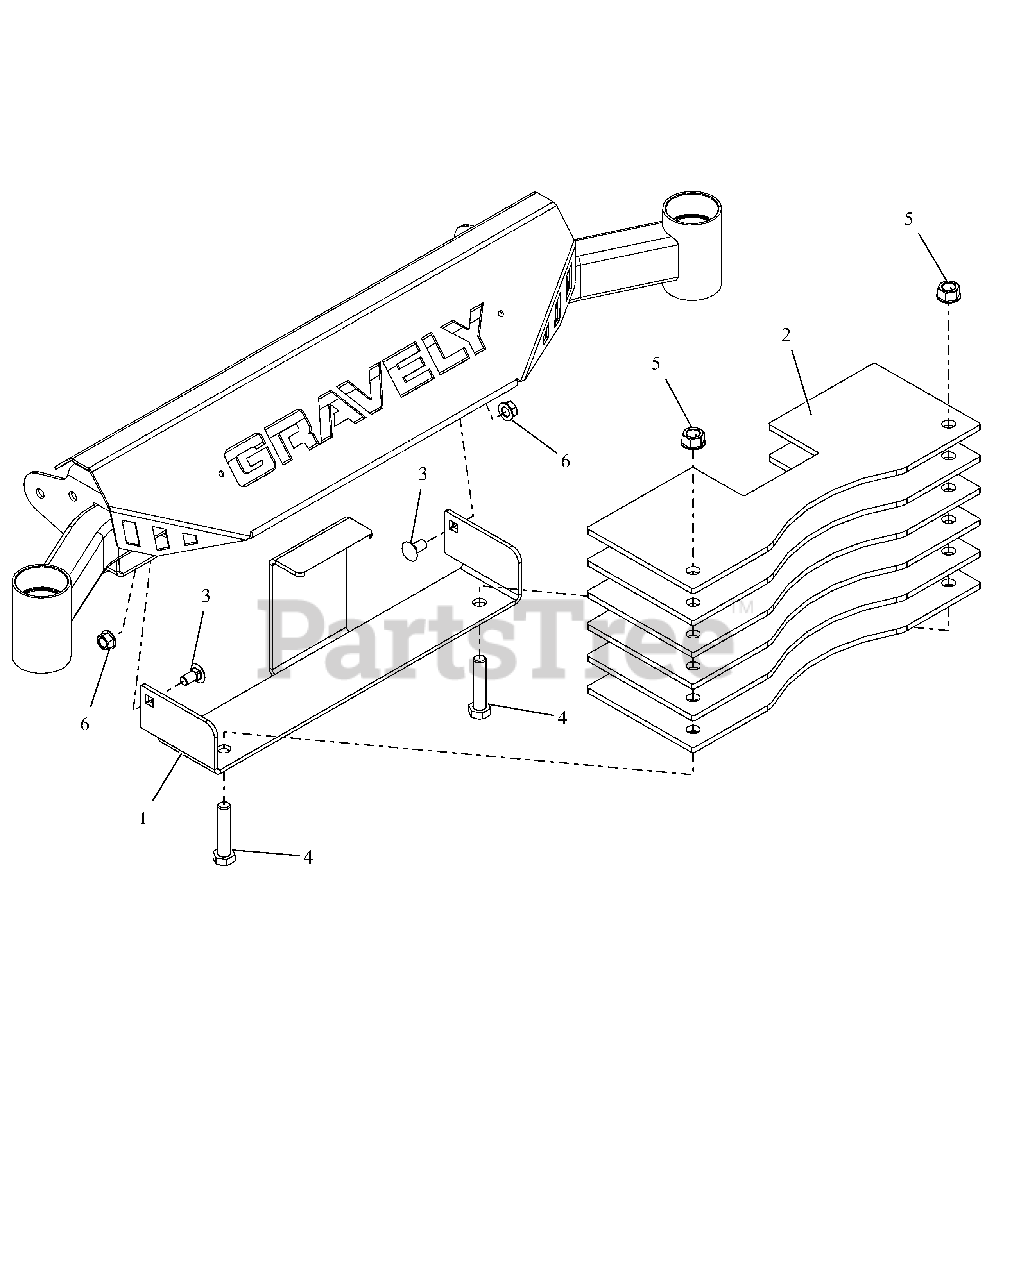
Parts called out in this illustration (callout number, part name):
1	BRACKET, WEIGHT -BAGGER
2	WEIGHT, BAGGER
3	@BLT-RDHDSQNK .38-16X.75 G5YZ
4	@BLT-HEX .50-13X2.25 GR5 YWZC
5	@NUT-LK-TOP-FLG .50-13 YWZC
6	@NUT-LK-TOP-FLG .38-16 YWZC
